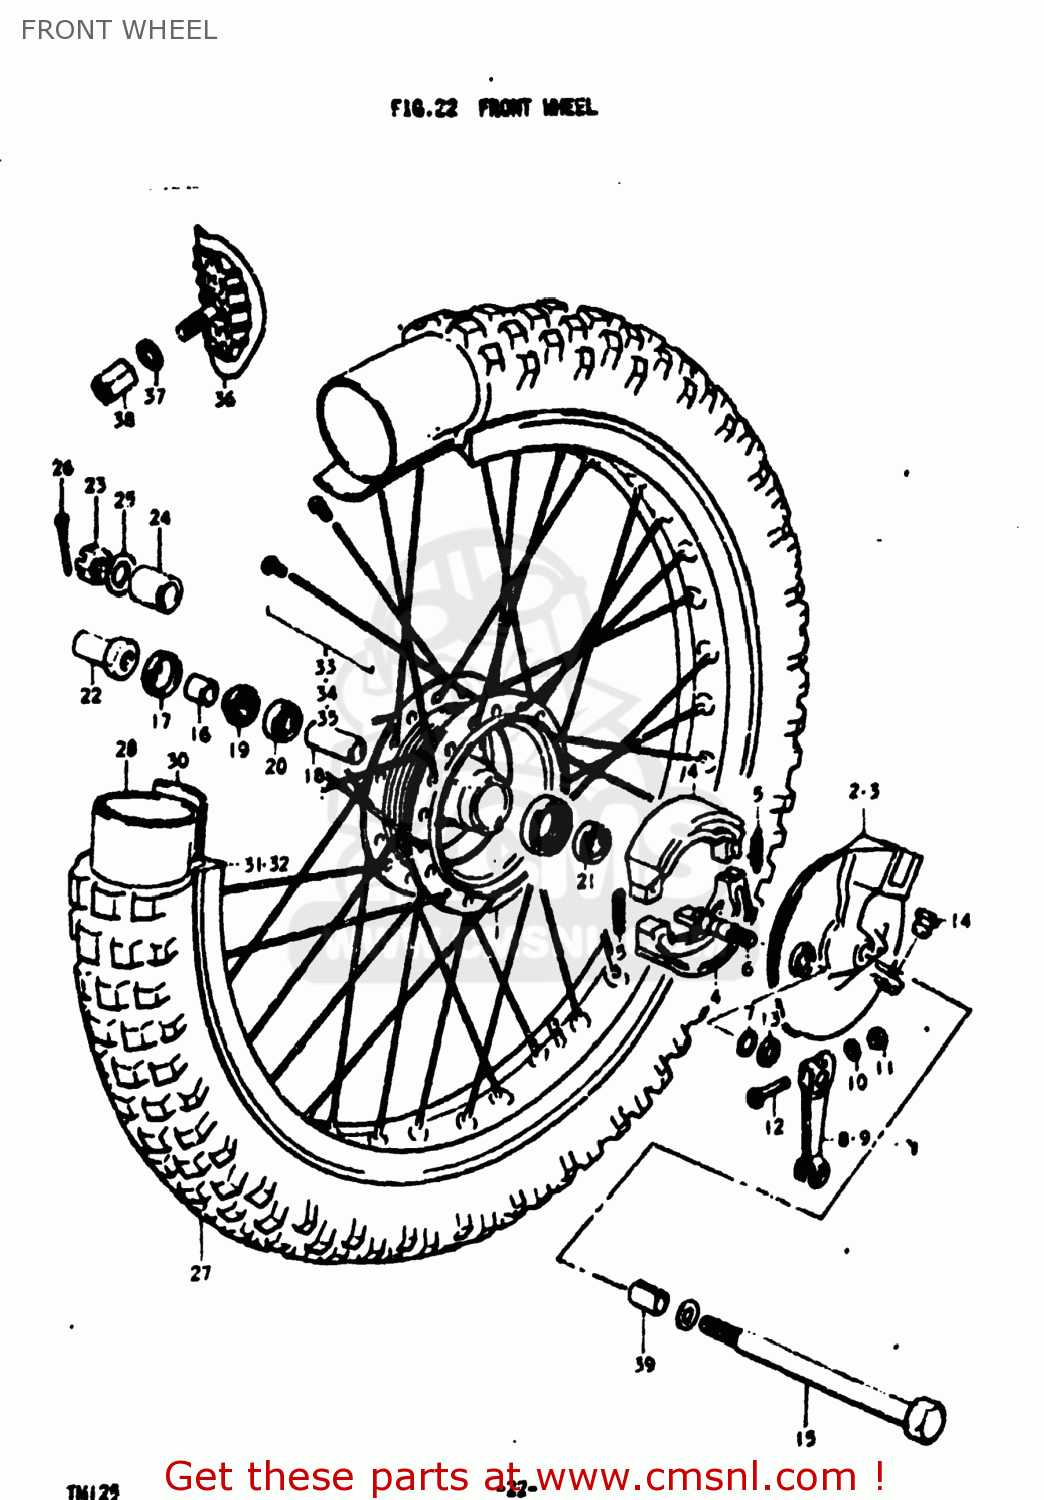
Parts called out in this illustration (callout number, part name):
0	HUB,FRONT
1	HUB,FRONT
2	PANEL,FRONT HUB
3	PANEL,FRONT HUB
4	SHOE,BRAKE
5	SPRING(L:34)
6	CAM,FRONT BRAKE
7	O RING(D:2.5,ID:11.4)
8	LEVER,FRONT BRAKE CAM
9	LEVER,FR BRAKE CAM
10	WASHER
11	NUT
12	BOLT
13	WASHER(12.5X20X1)
14	CAP(OD:17)
15	AXLE,FRONT
16	SPACER
17	DUST SEAL,FRONT HUB DRUM
18	SPACER (12.6X19X52)
19	OIL SEAL
20	BEARING
21	BEARING, LH
23	NUT, REAR AXLE
24	SPACER
25	WASHER
26	COTTER PIN
27	TIRE,FRONT
28	TUBE,INNER
29	TUBE
30	PROTECTOR,WHEEL,INNER
31	RIM,FRONT WHEEL
32	RIM,FRONT WHEEL
33	SPOKE SET,FRONT
34	SPOKE SET,FRONT
35	SPOKE SET,FRONT
36	STOPPER,BEAD
37	WASHER
38	NUT
39	SPACER,FRONT AXLE,LEFT
